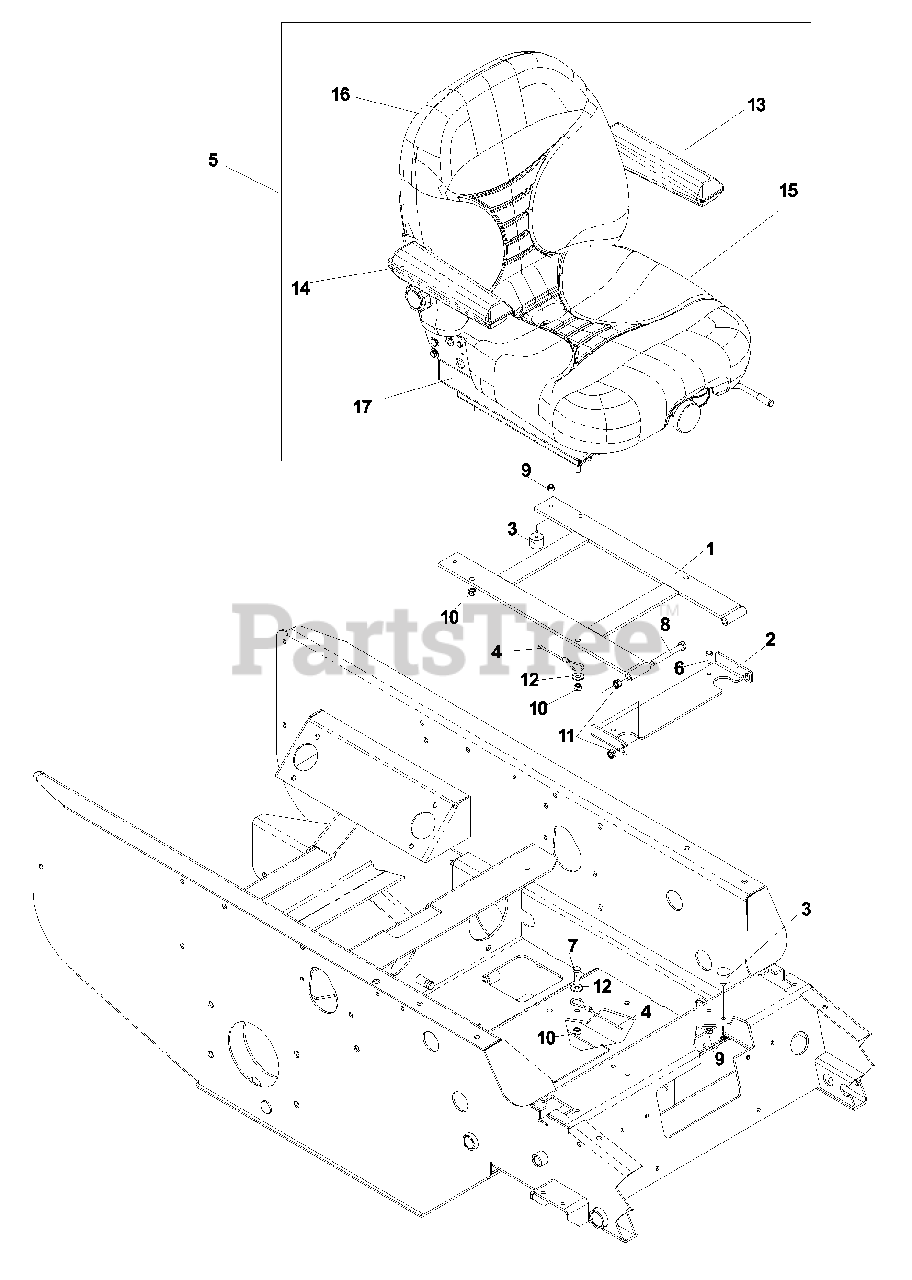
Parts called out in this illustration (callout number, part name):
1	Seat mount
2	Bracket w/decal, seat
3	Stud plate mount
4	Seat lanyard
5	Seat suspension
6	Bolt, 1/4-20 x 3/4
7	Bolt, 5/16-18 x 1
8	Bolt, 3/8-16 x 3
9	Nut, 1/4-20, nyloc
10	Nut, 5/16-18, nyloc
11	Nut, 3/8-16, centerlock
12	Washer, 5/16
13	Armrest kit, left
14	Armrest kit, right
15	Seat cushion kit
16	Back cushion kit
17	Slide kit, seat adjustment
